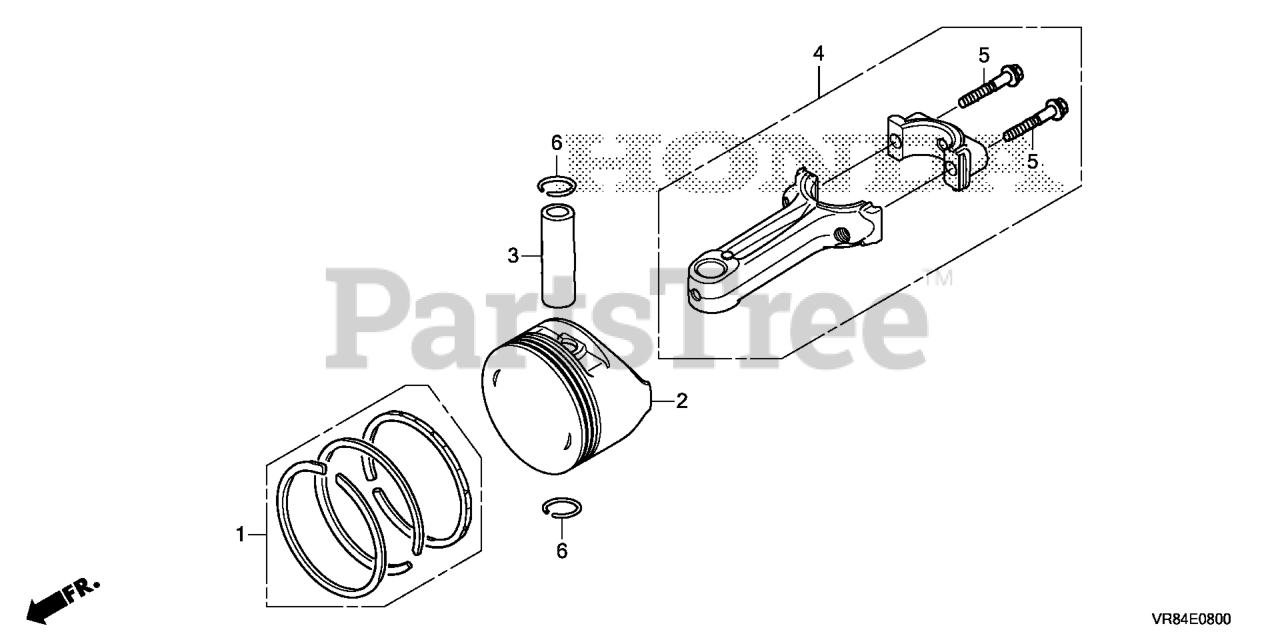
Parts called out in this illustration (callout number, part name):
1	RING SET, PISTON
3	PIN, PISTON
4	ROD ASSY., CONNECTING
5	BOLT, CONNECTING ROD
6	CLIP, PISTON PIN (13MM)
